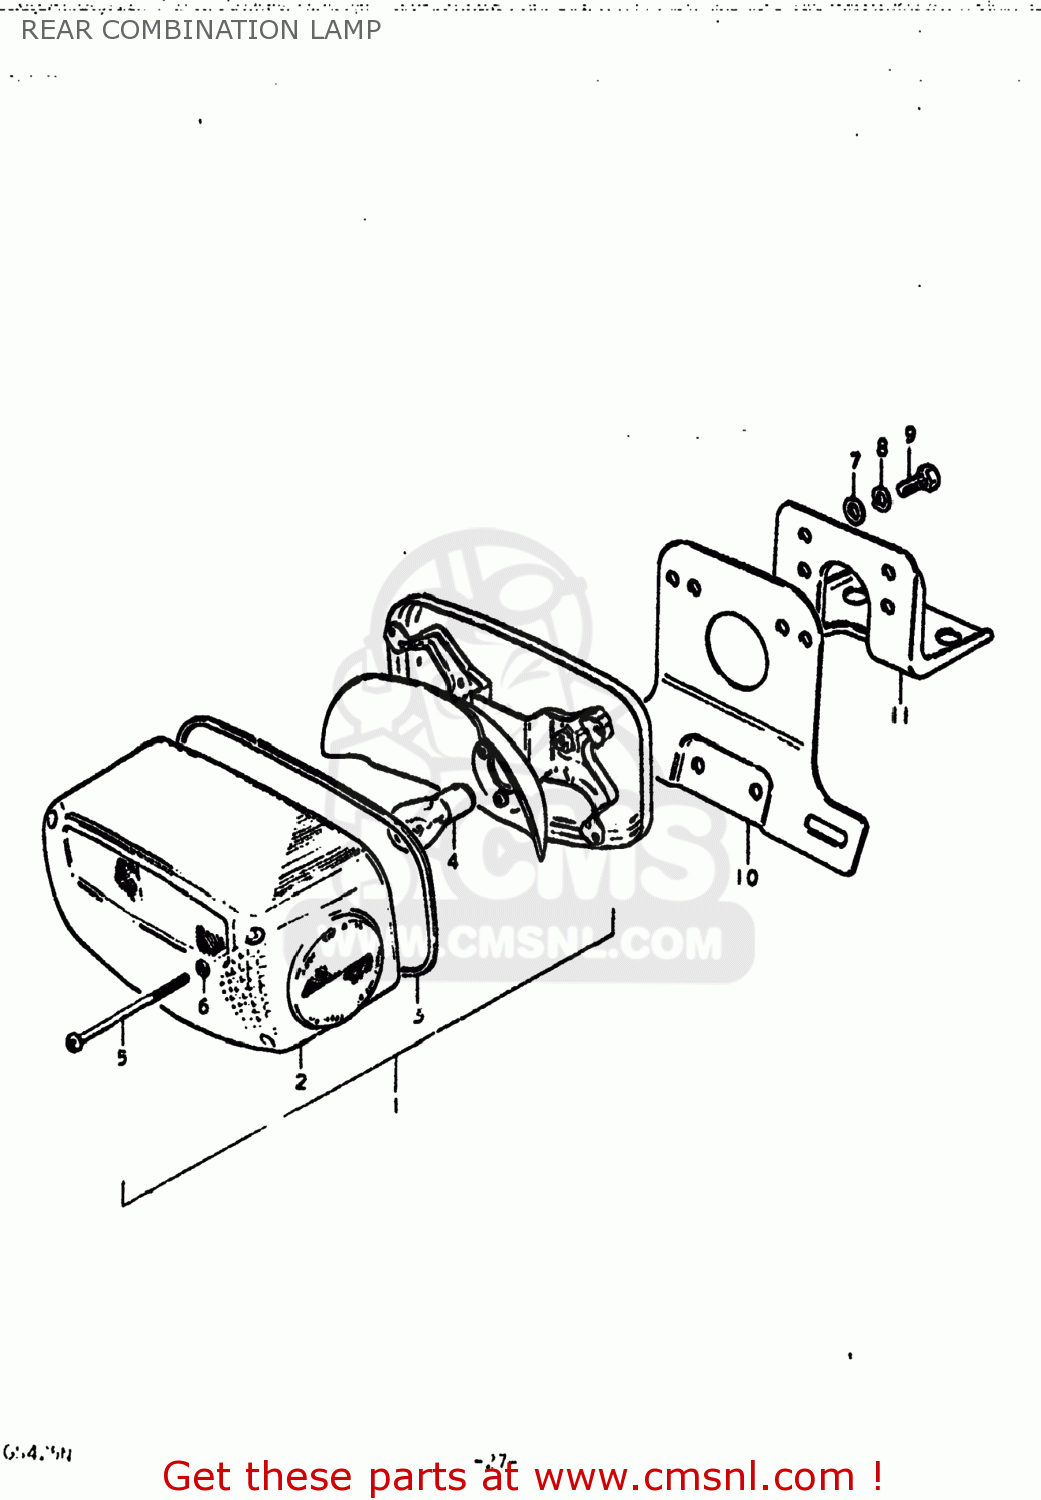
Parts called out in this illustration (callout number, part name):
1	LAMP ASSEMBLY,REAR COMBINATION
2	LENS,REAR COMBINATION LAMP
3	GASKET (NAS)
4	BULB(12V23W)
5	SCREW
6	GASKET (NAS)
7	WASHER
8	LOCK WASHER
9	BOLT
10	BRACKET,LICENSE PLATE
11	BRACKET,LICENSE PLATE
